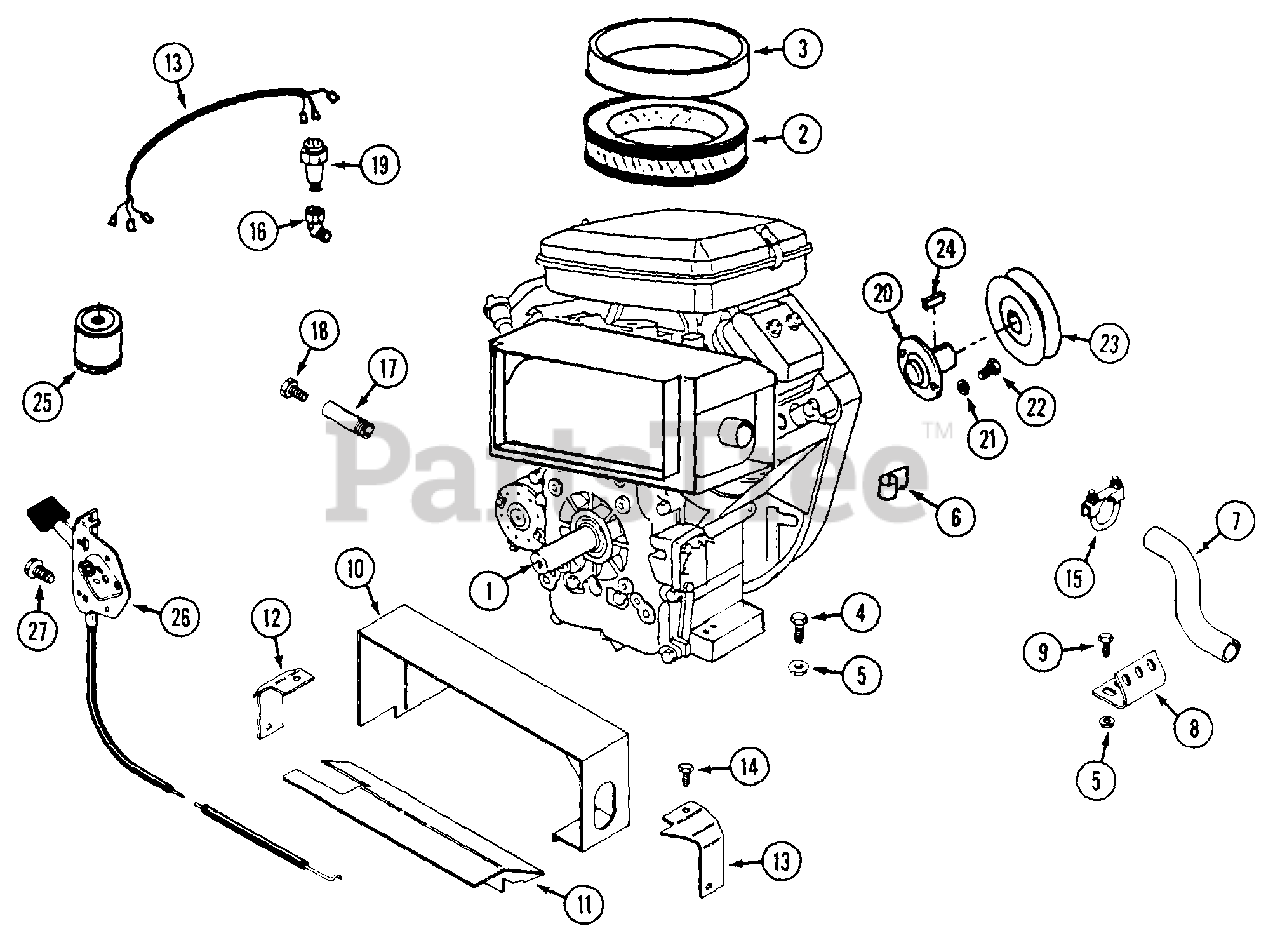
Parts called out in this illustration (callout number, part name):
1	ENGINE - Briggs & Stratton
2	ELEMENT - air cleaner
3	PRE-CLEANER
4	BOLT - 5/16"-18 x 1-1/4"
5	NUT - 5/16"-18 flange lock
6	CLIP - "J"
7	PIPE - exhaust
8	BRACKET - exhaust pipe
9	BOLT - 5/16"-18 x 1"
10	DUCT - muffler, upper
11	DUCT - bottom
12	SUPPORT - duct front
13	SUPPORT - duct rear
14	SCREW - M6 x 10
15	CLAMP - exhaust
16	FITTING - street elbow, 1/4" NPT 45°
17	NIPPLE - pipe 3.5"
18	PLUG - 1/2"-20
19	UNIT - oil sending
21	LOCKWASHER - 3/8"
22	BOLT - 3/8"-16 x 1"
23	PULLEY - engine
24	KEY - 1/4" x 1/4" x 1"
25	FILTER - oil
26	CABLE - throttle
27	SCREW - #12 x 1/2"
